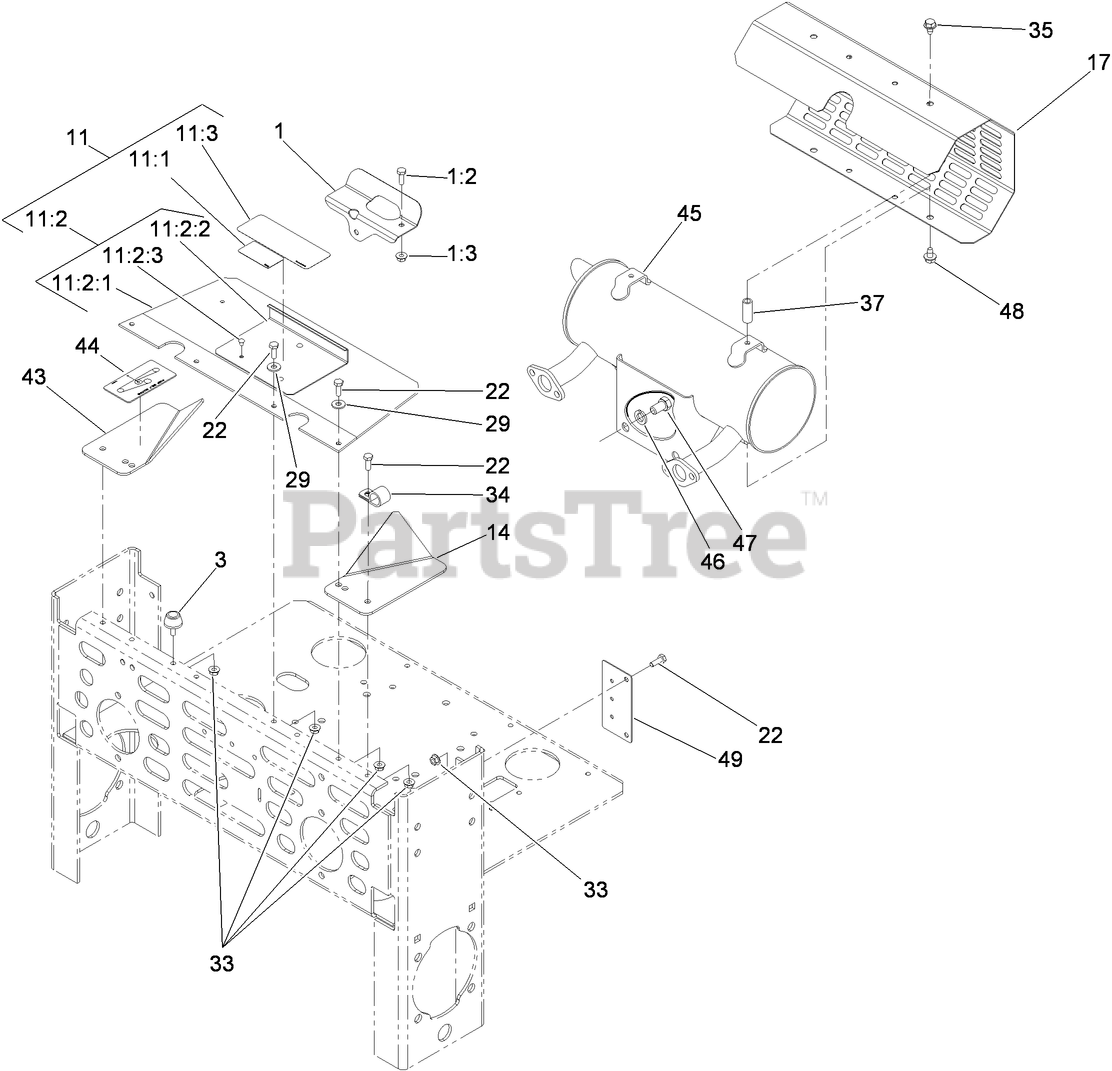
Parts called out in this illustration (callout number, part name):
1	Cable Heat Shield Kit
1:2	SCREW-HH
1:3	NUT-HF
3	BUMPER-RUBBER
11	SHIELD ASM
11:1	DECAL-IMPORTANT
11:2	SHIELD AND LIFT ASM
11:2:1	SHIELD-ENGINE
11:2:2	LIFT-SHIELD
11:2:3	RIVET-POP
11:3	DECAL-DEVICES, ROTATING
14	SUPPORT-FRONT COVER, LH
17	GUARD-MUFFLER
22	SCREW-HH
29	WASHER-FLAT
33	NUT-HF
34	CLIP-LOOM
35	SCREW-HWH
37	SPACER
43	SUPPORT-FRONT COVER, RH
44	DECAL-ROUTING, BELT
45	MUFFLER
46	WASHER-LOCK
47	SCREW-HH
48	SCREW
49	MOUNT-RELAY
